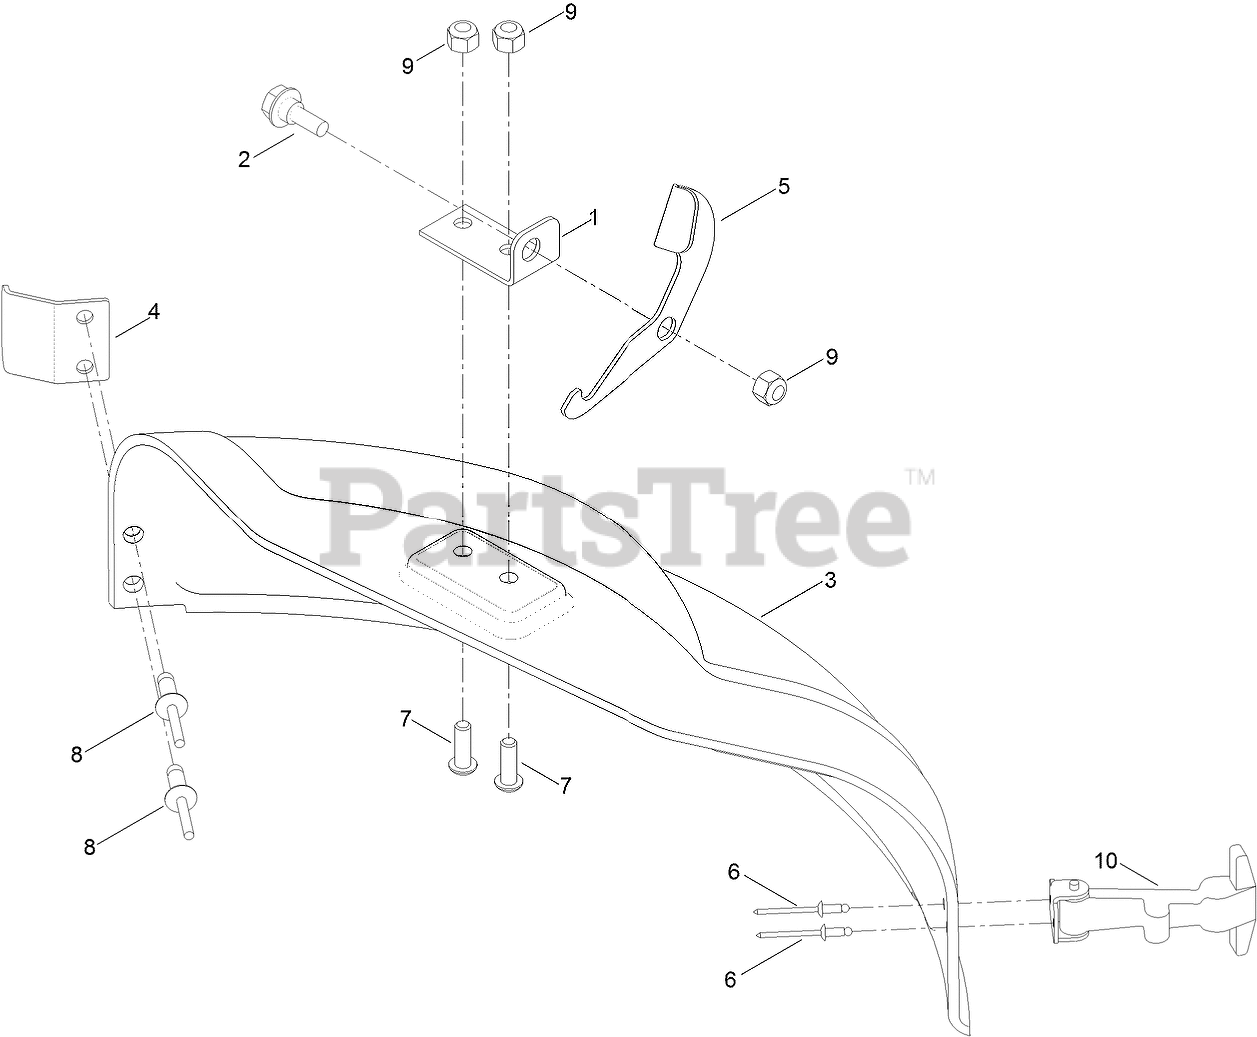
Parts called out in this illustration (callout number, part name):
1	PLATE-PIVOT
2	SCREW-SHOULDER,HWH
3	PLUG-MULCH, 42 INCH
4	BRACKET-ELBOW
6	RIVET-POP
7	SCREW-HSBH
8	RIVET-BLIND
9	NUT-LOCK, NI
10	HANDLE ASM
